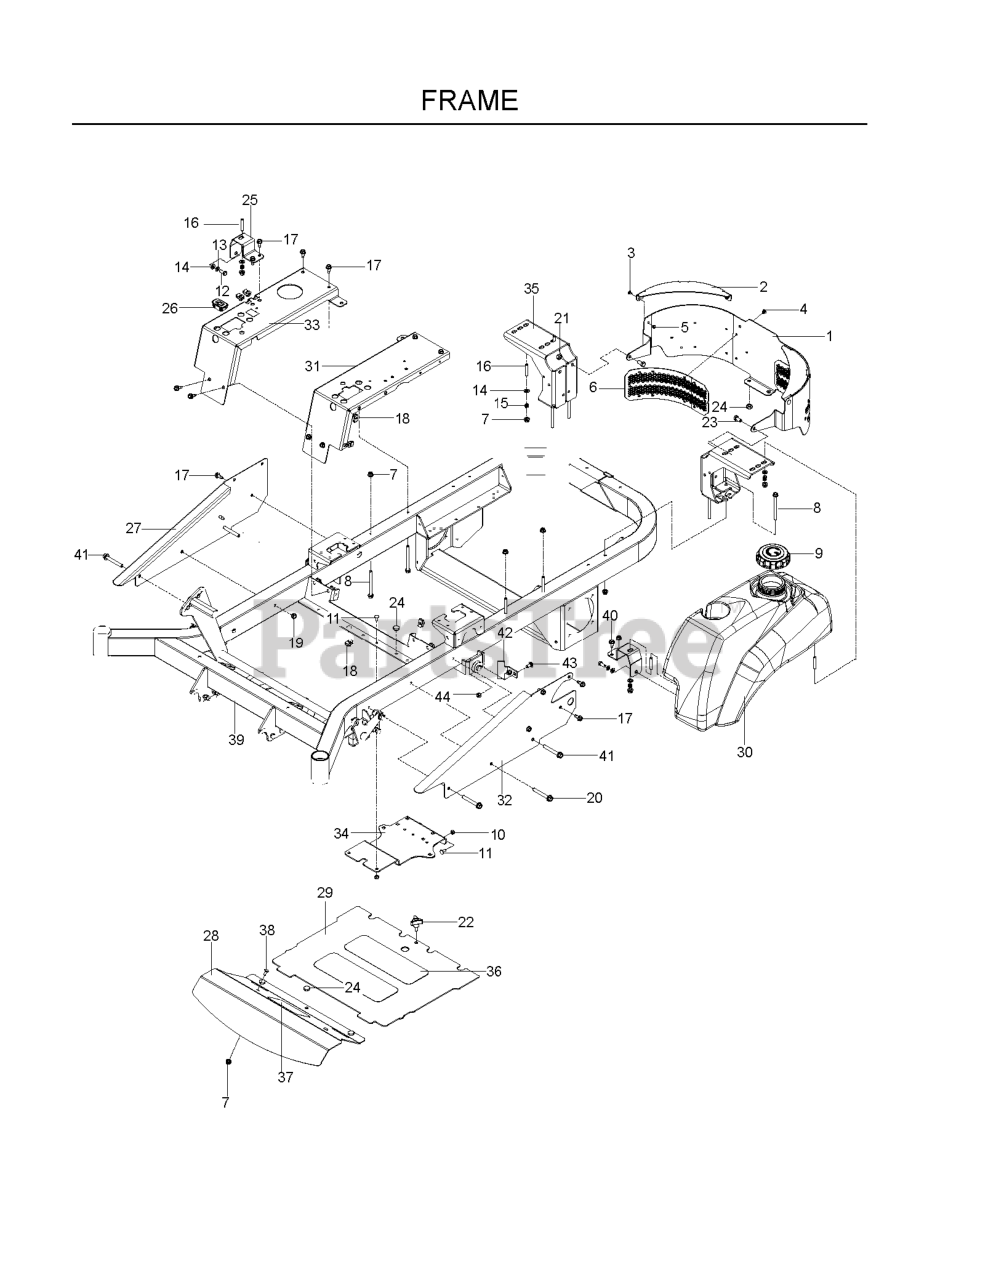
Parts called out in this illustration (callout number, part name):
1	GUARD, REAR
2	SUPPORT, TOP
3	RHSSNB 1/4-20 X 1/2
4	RIVERT, 3/16, STAVEX
5	JAM NUT 1/4C (2 2 PW01)
6	PANEL, HEX, RR
7	5/16-18 NYLOC FLANGE NUT
8	HHFS 5/16-18 X 3 3/4
9	FUEL CAP, HTC
10	NUT.1/4-20.HEX.NYLOC.ZD
11	RHSSNB, 1/4-20X5/8
12	HCS 5/16C X 3/4
13	WASHER.LOCK.HVY.HLCL.SPR.5/16
14	FLAT WASHER 5/16 SAE
16	STUD, 5/16C
17	BOLT 5/16-18 X 3/4
18	U-CLIP 5/16-18 NUT RETAINER
19	NUT HEX 3/8-16 NYLON, THIN
20	HHFS 3/8-16 X 2 3/4
21	NUT 3/8-16 NYLOC
22	KNOB W/STUD
23	SCREW 3/8C X 3/4 HEX CAP
24	GROMMET, BUMPER
25	SUPPORT, TANK, BLK
26	HOUR METER
27	SIDE.RT.ORANGE
28	PLATE, FOOTREST
29	PLATE, FLOOR W/DECALS
30	LEFT TANK W/CUP HOLDER
31	PANEL, FILLER, LT
32	SIDE.LT.ORANGE
33	PANEL, FILLER, RT
34	BATTERY MOUNT
35	MOUNT, TANK, RR
36	ANTI-SKID PAD
38	RHSNB 5/16C X 1
39	FRAME W/DECALS 52", 61"
40	RP BLT 5/16-18 X 1 THRD FORM D
41	HHFS 3/8-16 X 2.5 GR 5 ZD
42	STOP, DECK, EZ+
43	BOLT 5/16C X 3/4" CARRIAGE
44	NUT 5/16 NYLOC
